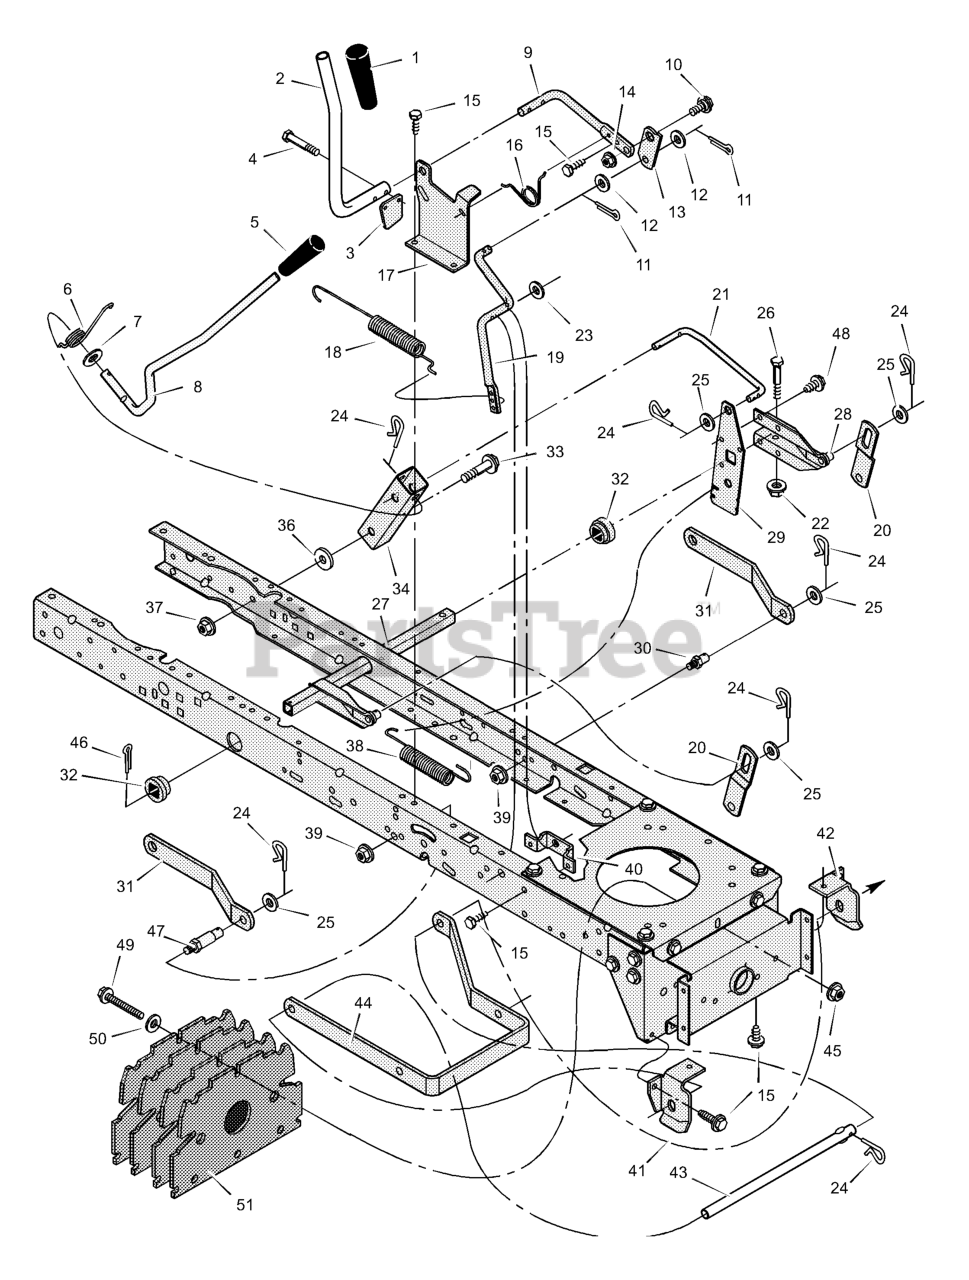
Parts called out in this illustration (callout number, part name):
1	Grip
2	Handle, PTO
3	Pad, Switch
4	Screw, Hex
5	Grip
8	Handle, Lift
9	Lever, PTO
10	Bolt, Shoulder
11	Pin, Cotter
12	Washer
13	Link, PTO
14	Nut, Flange
17	Bracket, PTO
19	Crank, PTO
20	Link, Lift
21	Link, Lift Handle
22	Nut, Flange
24	Pin, Hair
26	Bolt, Hex
27	Arm Assembly, Right Lift
28	Arm, Right Lift
29	Plate, Lift Arm
30	Pin
31	Bracket, Rear Suspension
32	Bushing, Lift Tube
33	Bolt, Shoulder
34	Bracket, Pivot
37	Nut, Flange
39	Nut, Flange
40	Bracket, PTO
41	Hanger, Right Deck
42	Hanger, Left Deck
43	Rod, Hanger
44	Hanger, Front
45	Nut, Flange
46	Pin, Cotter
47	Pin, Threaded Shoulder
49	Bolt, Hex
51	Plate, Weight
